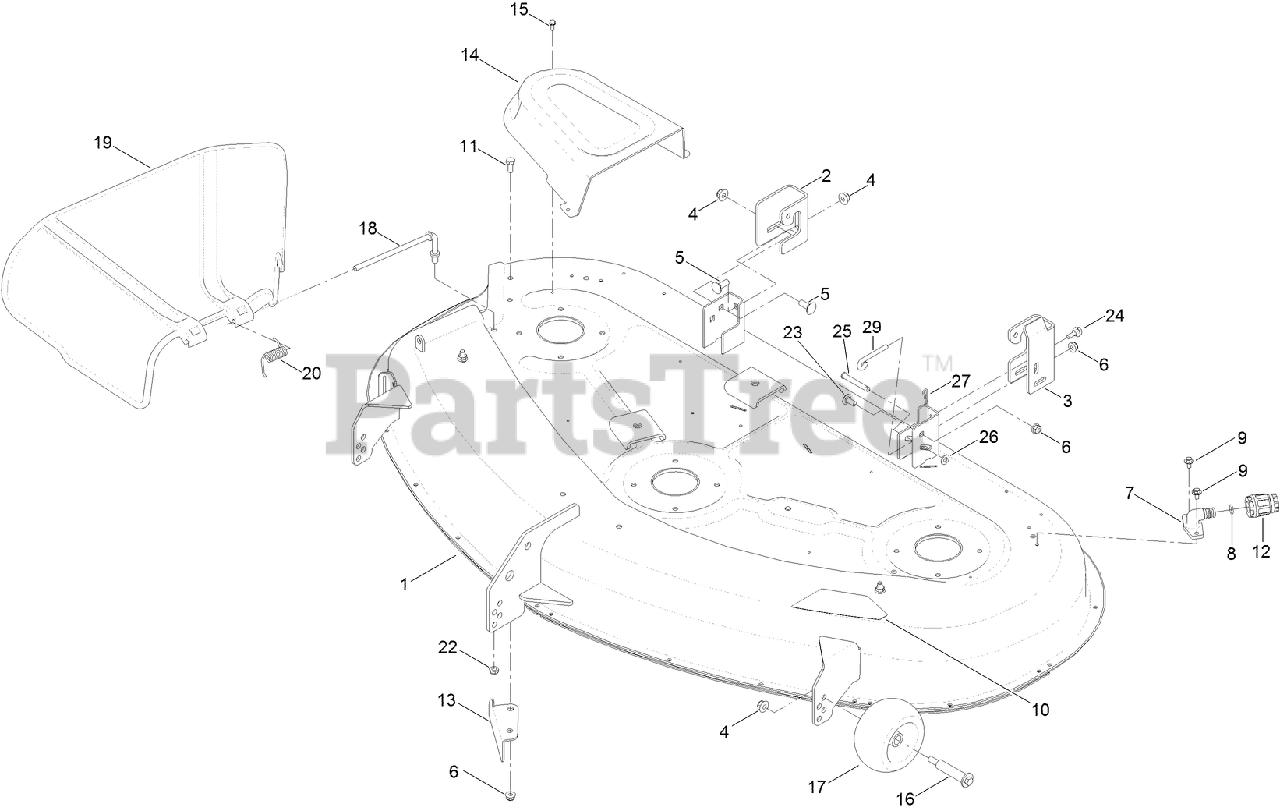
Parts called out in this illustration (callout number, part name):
1	54 INCH DECK ASM
2	BRACKET-HANGER, RH
3	BRACKET-HANGER, LH
4	NUT-HF, NI
5	BOLT-CARR
6	NUT-HF, NI
8	O-RING
9	SCREW-HHFTF
10	DECAL-DECK
11	SCREW-HH
12	CONNECTOR-HOSE
13	BAFFLE-CUTOFF
14	COVER-BELT
15	SCREW-TAPTITE
16	BOLT-SHOULDER
17	ROLLER-SCALP, ANTI
18	ROD-PIVOT
19	DEFLECTOR
20	SPRING-TORSION
23	SCREW-CARR
24	SCREW-SHOULDER,HWH
25	PIN-CLEVIS
26	WASHER-PLAIN
27	PIN-COTTER
29	ROD-LEVEL, DECK
